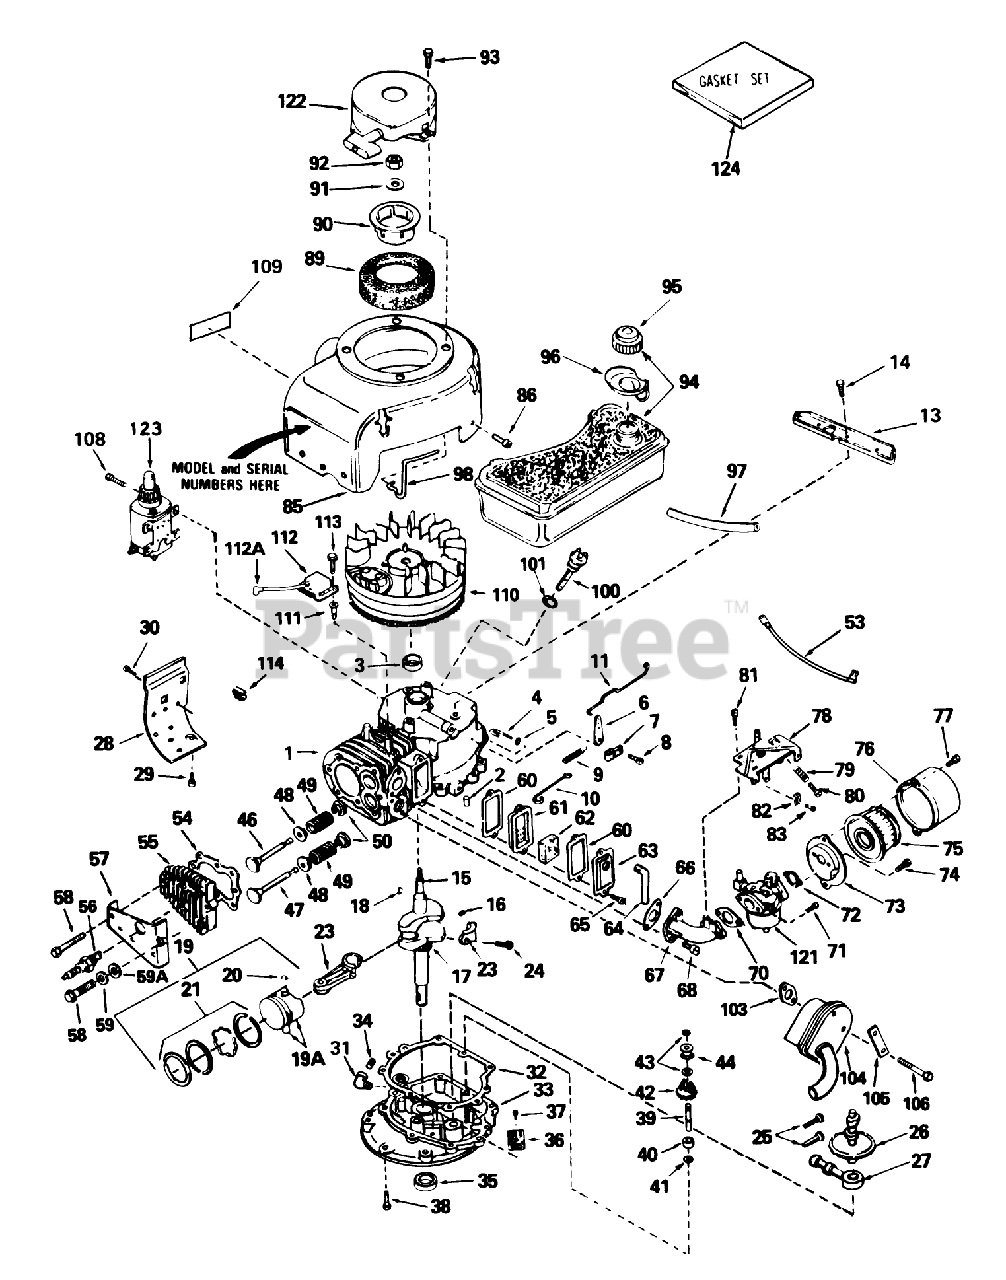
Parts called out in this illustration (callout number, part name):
1	Cylinder Assy., (Incl. Ref. #2, 3, 100 101)
2	Pin-Dowel
3	Oil Seal
4	Rod, Governor (Incl. Nos. 146)
5	Washer-Flat
6	Lever-Governor
7	Clamp-Lever, Governor
8	Screw
9	Spring Governor
10	Link Governor Spring
11	Link Governor
13	Bracket-Blower Housing
14	Screw (1/4-20x19/32)
15	Crankshaft Assy. (Incl. Ref. #16 17)
16	Pin, Groove
17	Gear-Crankshaft
18	Key-Flywheel
19	Piston, Pin Ring Assy. (Std.) (Incl. Ref. #19A, 20 21)
19	Piston, Pin Ring Assy. (.010 oversize) (Incl. Ref. #19A, 20 21 )
19	Piston, Pin Ring Assy. (.020 oversize) (Incl. Ref. #19A, 20 21)
19A	Piston Pin Assy. (Std.) (Incl. Ref. #20)
19A	Piston Pin Assy. (.010 oversize) (Incl. Ref. #20)
19A	Piston Pin Assy-. (.020 oversize) (Incl. Ref. #20)
21	ORing
21	Ring Set (.010" OS)
21	Ring Set (.020" OS)
23	Rod Assy., Connecting (Incl. Nos. 10 18)
24	Bolt-Connecting Rod
25	Lifter-Valve
26	Screw
27	Pump, Oil
28	Extension-Blower Hsng.
29	Screw
30	Screw
31	Street Elbow (90 degrees) (Can be purchased locally)
32	Gasket-Cover, Cylinder
33	Flange Assy., Mounting (Incl. Ref. #34 thru 37 39)
34	Plug-Drain, Oil (SQH 1/4-18)
35	Seal-Oil
36	Screen-Oil Filter
37	Screw
38	Screw (1/4-20 x 1-1/4)
39	Shaft, Governor
40	Spacer Assy. Governor (Incl. Ref. #41)
41	Washer-Flat
42	Governor Gear ASM
43	Ring-Retaining
44	Spool-Governor
46	Valve, Intake (Standard)(Incl. No. 9)
46	Valve, Intake (1/32" oversize)(Incl. No. 9)
47	Valve, Exhaust (Standard)(Incl. No. 9)
47	Valve, Exhaust (1/32" oversize)(Incl. No. 9)
48	Cap-Spring, Valve
49	Spring-Valve
50	Keeper-Spring, Valve
53	Wire-Ground
54	Gasket-Cylinder Head
55	CYLINDER HEAD
56	Plug, Spark (J17LM or equiv.)
56	Plug, Spark (Champion RCJ-8)
57	Cover-Head, Cylinder
58	Screw (5/16-18 X 2-1/2)
59	Washer-Belleville
59A	Washer-Flat
60	Gasket-Breather
61	Body-Breather
62	Element-Breather
63	Cover-Valve
64	Tube-Breather
65	Screw
66	Gasket-Intake
67	Pipe-Intake
68	Screw (T-30, 5/16-18x1-3/32)
70	Gasket
71	Screw-Hex Hd.
72	Gasket
73	Bracket
74	Screw (10-32 x 1/2)
75	Element
76	Body-Air Cleaner
77	Screw
78	Control Assy.Speed (Incl. Ref. #79 80)
79	Spring-Compression
80	Screw
81	Screw (10-24 x 9/16)
82	Conduit
83	Screw (10-32 x 3/8)
85	Housing-Blower
86	Screw
89	Screen-Starter
90	Cup-Starter
91	Washer-Belleville
93	Screw
94	Tank Assy., Fuel (Incl. No. 127)
95	Cap-Fuel
96	Deflector-Fuel
97	Line-Fuel (8.62)
98	Clamp, Tank Holdown
100	Dipstick, Oil (Incl. No. 45)
101	Gasket
103	Gasket Exhaust
104	Muffler
105	62513 SNWTHWR W/284
106	Screw Hex Hd.
108	Screw
109	Decal-Instruction
110	Flywheel
112	Solid State
112A	Cover-Spark Plug
113	Screw
114	Clip, Spring
121	Carburetor
122	tarter-Rewind
123	Tine Shaft
124	Gasket Set
